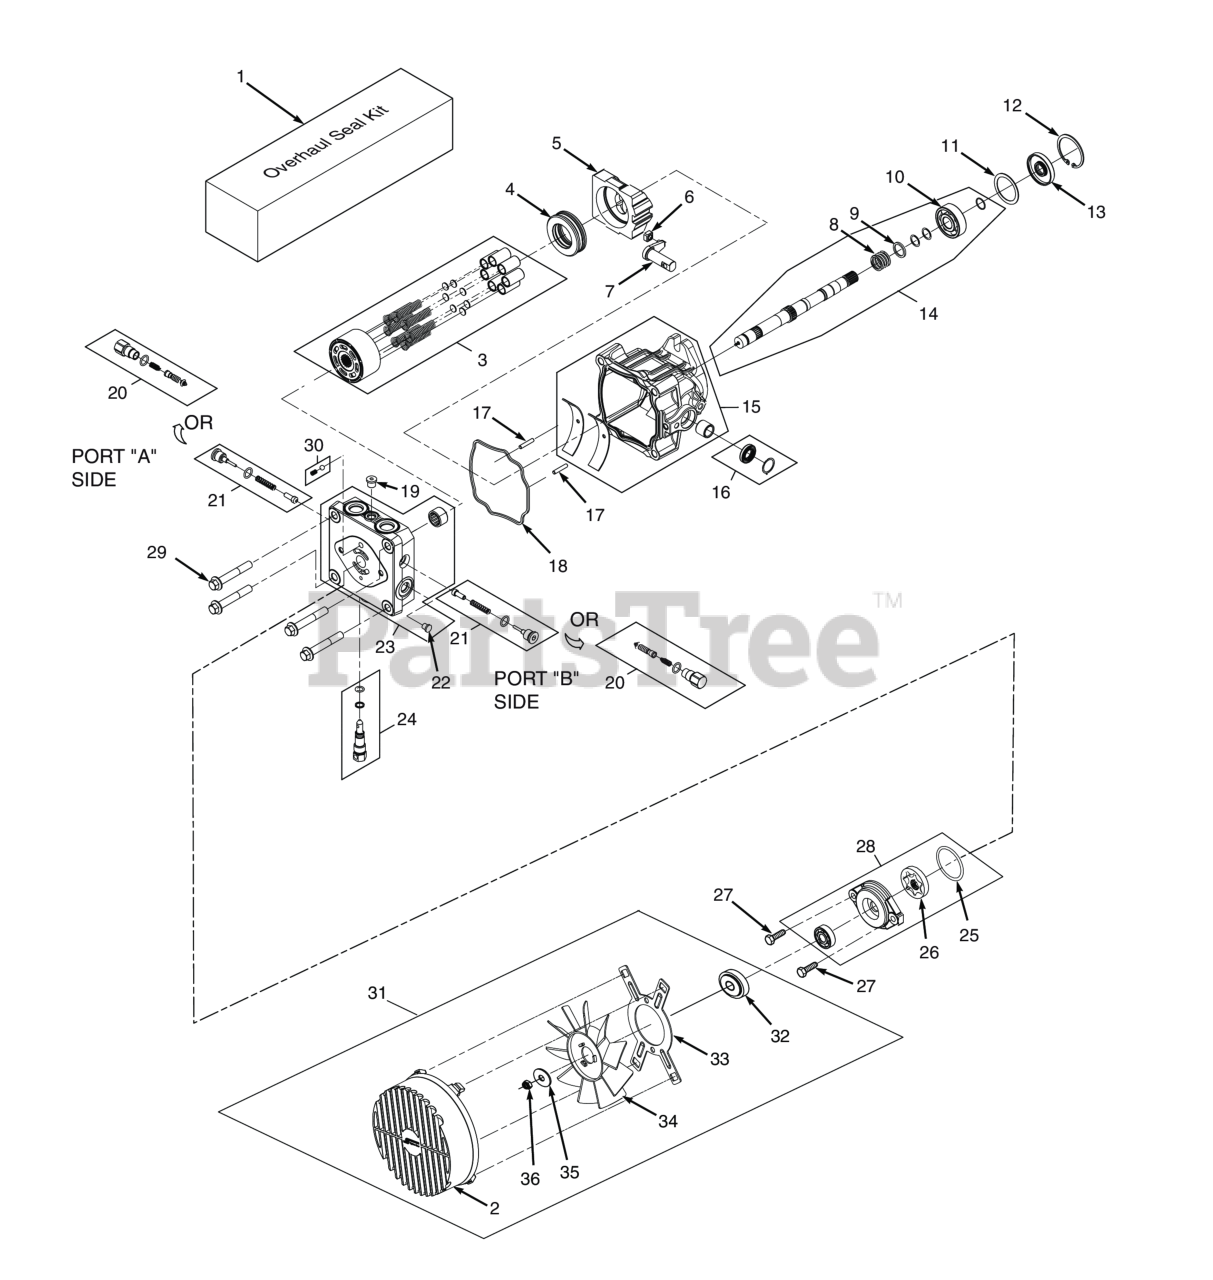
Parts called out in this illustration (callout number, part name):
1	Overhaul Seal Kit
2	Fan Cover
3	Cylinder Block Kit - 16cc
4	Thrust Ball Bearing Assembly
5	Variable Swashplate
6	Slot Guide
7	Trunnion Arm
8	Spring Block
9	Block Thrust Washer
10	Shaft Ball Bearing
12	Retaining Ring
13	Lip Seal
14	Kit, Pump Shaft (keyed thru taper)
15	Housing Kit
16	Trunnion Seal Kit
17	Straight Headless Pin
18	O-Ring
19	Straight Thread Plug
20	System Check Relief Kit, port "B" on Left Hand Pump, port "A" on Right Hand Pump
21	Shock Valve Kit (.024" Orifice)
22	Straight Thread Plug
23	End Cap Kit
24	Bypass Valve Kit
25	O-Ring, Charge Pump Cover
26	Gerotor Assembly (.19 cu.in./rev.)
27	Socket Head Cap Screw (M8 x 1.25-25mm)
28	Charge Pump Kit (.19 STD. Splined)
29	Hex Screw, Flanged Head (M10 x 1.50-65mm)
30	Charge Relief Valve Kit
31	Fan Kit
32	Washer
33	Bracket, Shroud
35	Washer
